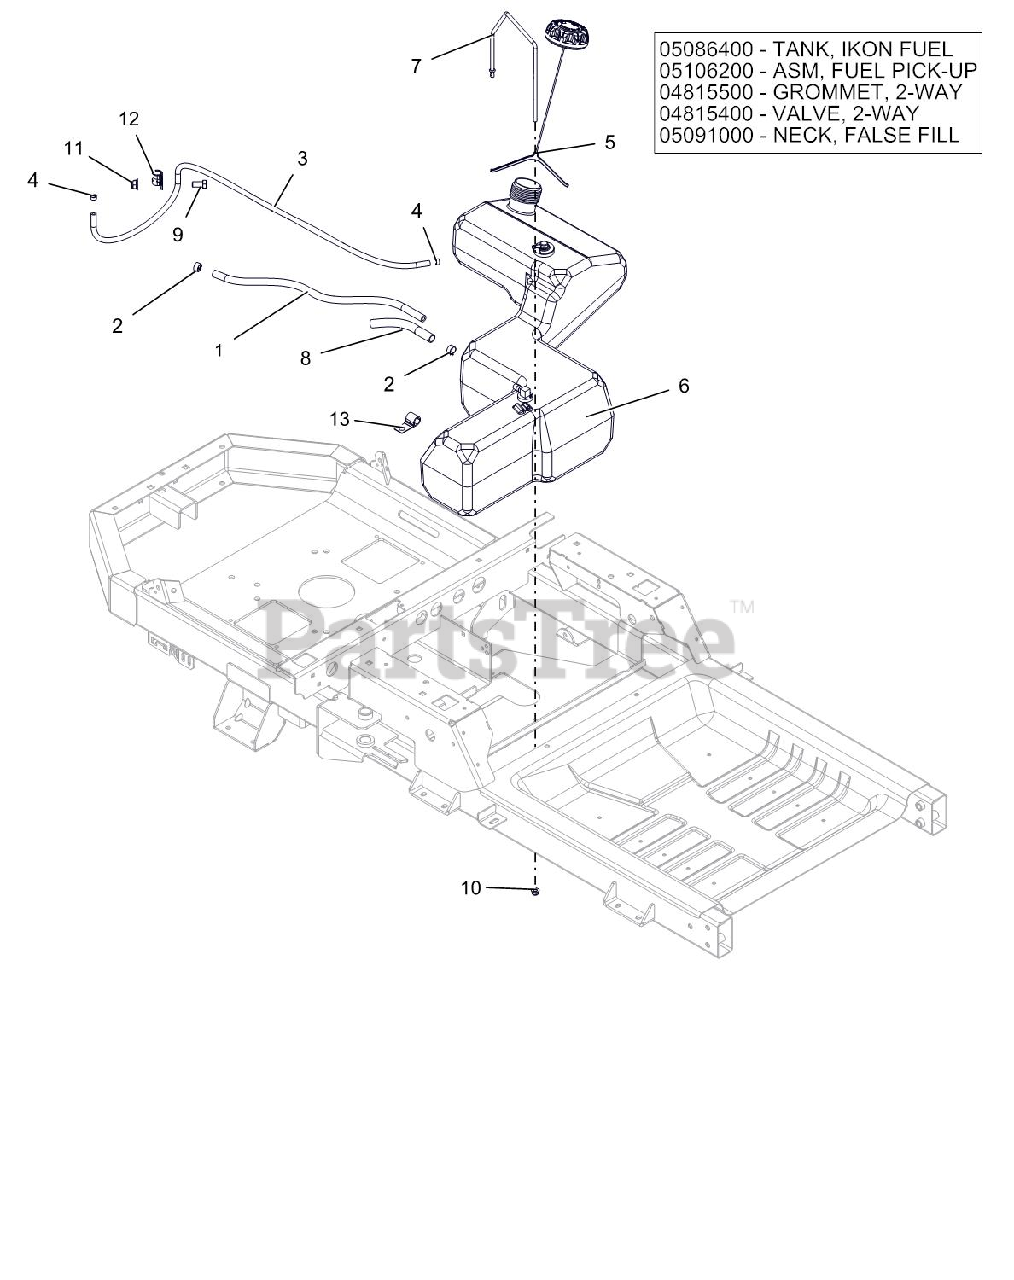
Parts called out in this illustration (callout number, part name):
1	HOSE, .25 LOW-PERM BULK GAS
2	CLAMP, FUEL LINE
3	HOSE, .188 LOW-PERM BULK GAS
4	CLAMP-HOSE, SPRING .188
5	CAP, FUEL VENT-IN 2.25" RATCH.
6	VALVE, 2-WAY
6	GROMMET, 2-WAY
6	ASSEMBLY, FUEL TANK IKON(2017)
6	TANK, IKON FUEL (2017)
6	ASM, IKON FUEL PICK-UP
6	NECK, FALSE FILL-2017 IKON
7	BRKT, FUEL TANK HOLD DOWN
8	WRAP, ANTIABRASION .5X.064WALL
9	@BLT-HEX .38-16X.75 GR5 YWZC
10	@NUT-LK-NYL-FLG .25-20 YWZC
11	@NUT-LK-NYL-FLG .38-16 YWZC
12	CLAMP, CUSHIONED STEEL
13	J-CLAMP
